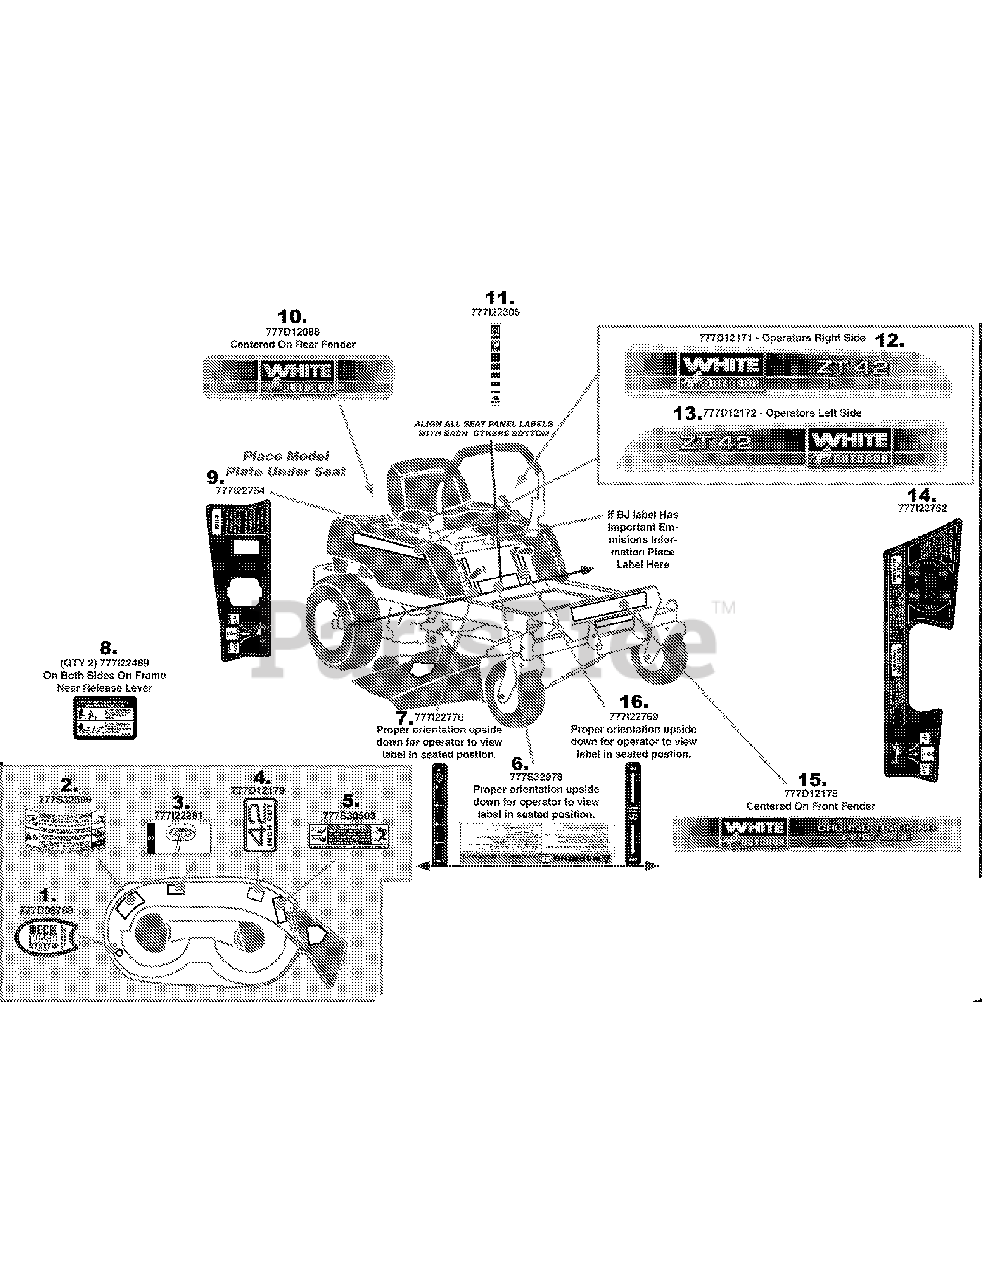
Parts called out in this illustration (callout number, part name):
1	LABEL:RIDER:WHITE
2	LABEL-RZT DECK WARNG CURVE
3	LABEL-BELT ROUTE
4	LABEL-RZT DECK 42"
5	LABEL-DANGER CHUTE
6	LABEL-COMMON WARNING
7	LABEL-HANDLE HEIGHT
8	LABEL-TRNMSN RELEASE
9	LABEL-RH CONTROL
10	LABEL-RIDER REAR FENDER WHITE
11	LABEL-THROTTLE
12	LABEL-ZT 42 WHITE OUTDR RH
13	LABEL-ZT 42 WHITE OUTDR LH
14	LABEL-LH CONTROL
15	LABEL-RZT FRONT WHITE LOGO
16	LABEL-PARK BRAKE
